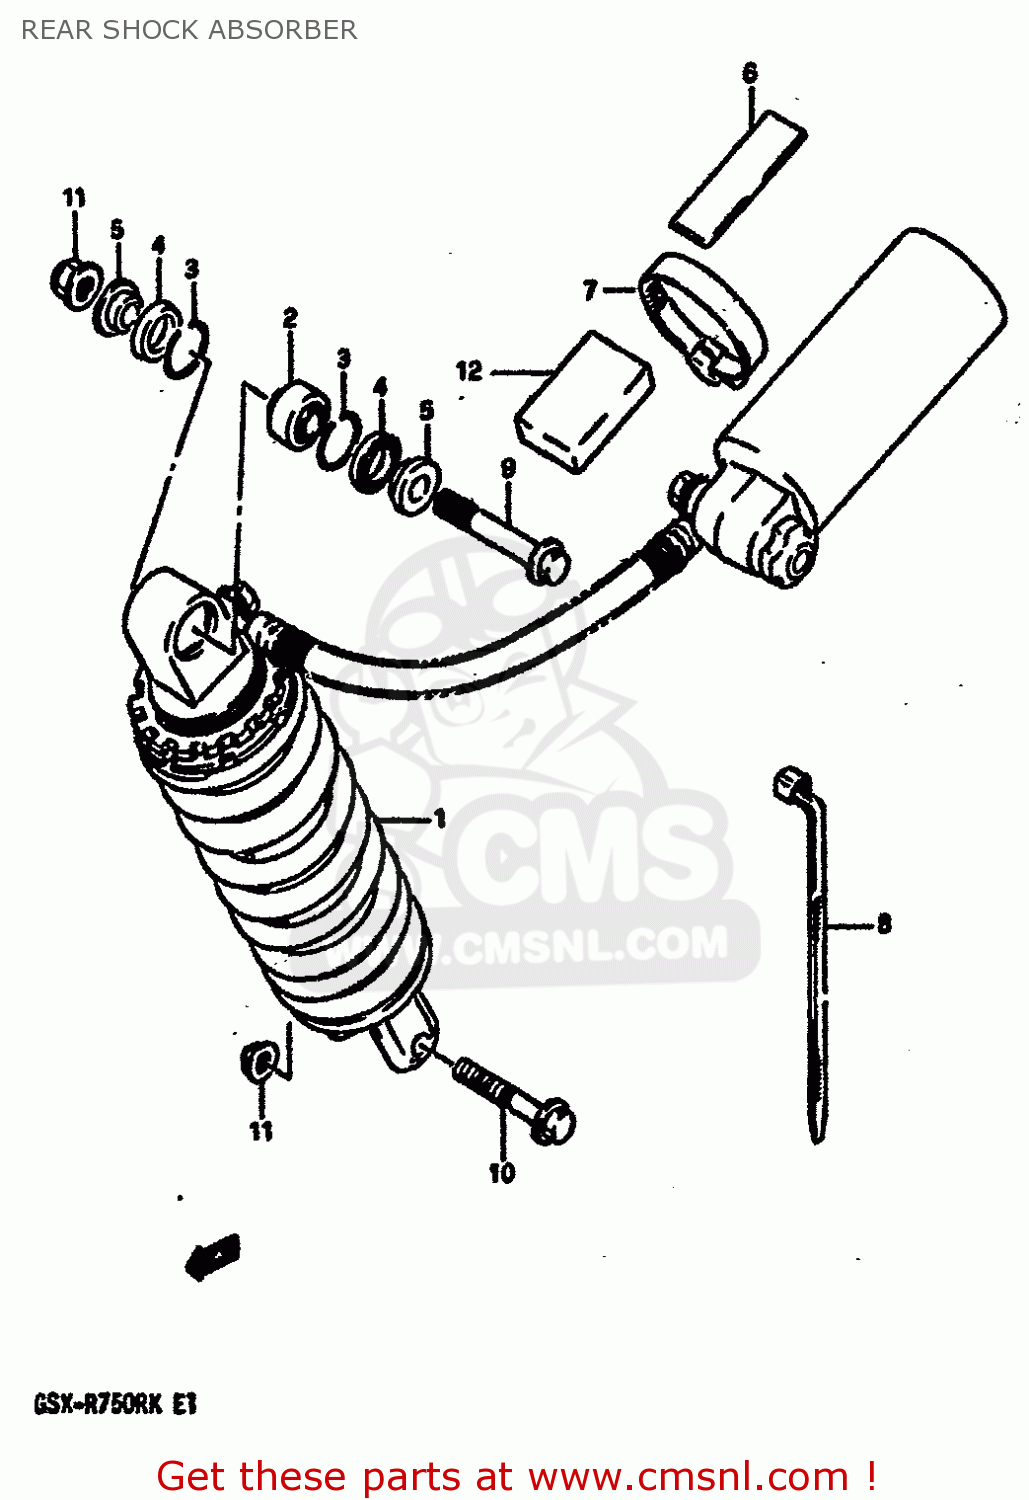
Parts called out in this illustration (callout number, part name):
1	ABSORBER ASSY,REAR SHOCK
2	BEARING,REAR SHOCK ABSORBER
3	RING
4	DUST SEAL
5	COLLAR
6	CUSHION,RESERVOIR TANK
7	CLAMP
8	CLAMP(L:165)
9	BOLT
10	BOLT(10X54)
11	NUT
12	CUSHION,TANK
